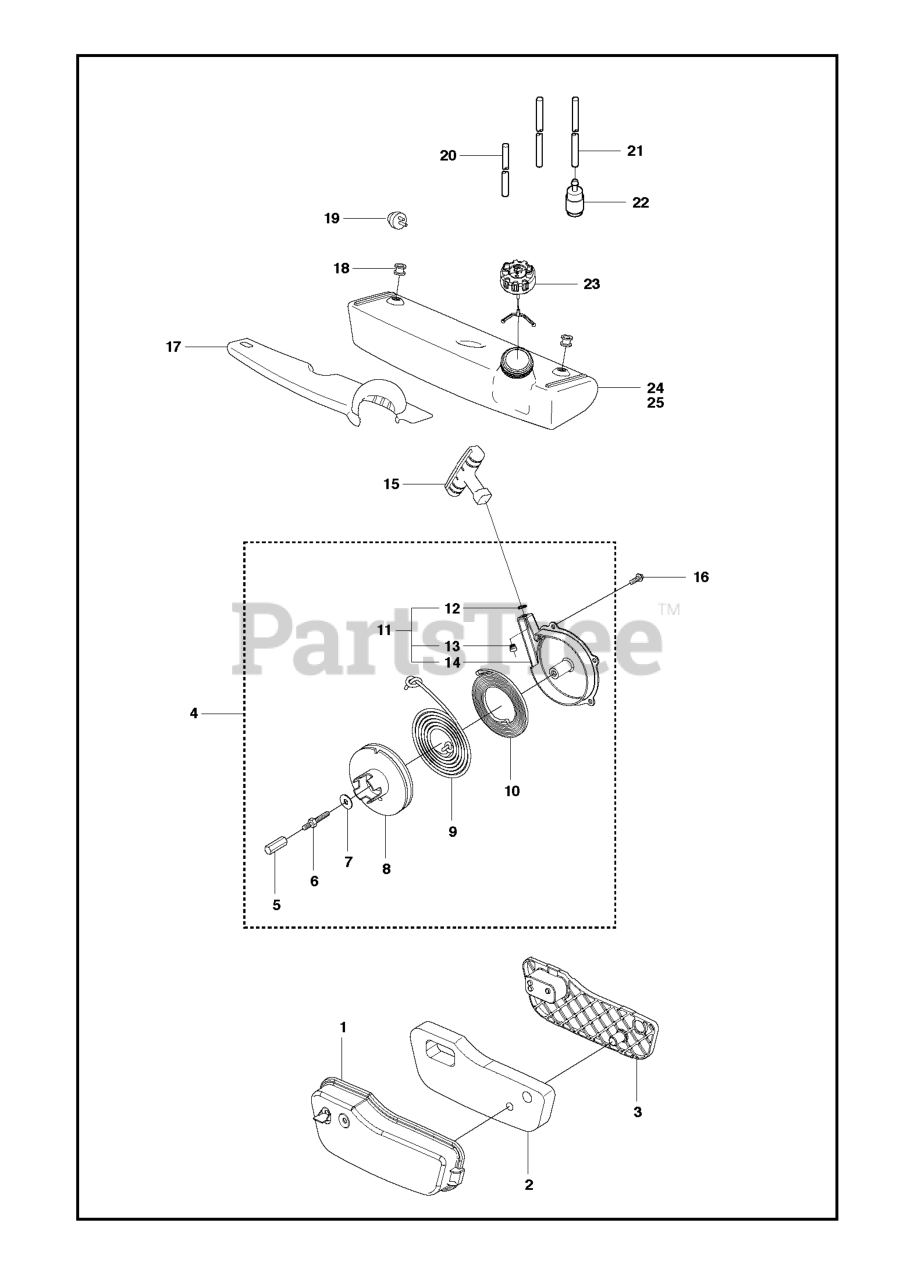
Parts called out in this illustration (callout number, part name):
2	AIR FILTER
3	NET AIR FILTER
4	STARTER DEVICE
8	STARTER PULLEY
9	STARTER ROPE
10	RECOIL SPRING
12	RETAINING RING
13	SLEEVE, STARTER HOUSING
14	STARTER DEVICE
15	STARTER HANDLE
18	FUEL TANK BUSHING
19	AIR PURGE BUBBLE
22	RP FUEL FILTER
23	FUEL CAP ASSY
24	TANK UNIT
25	USA
